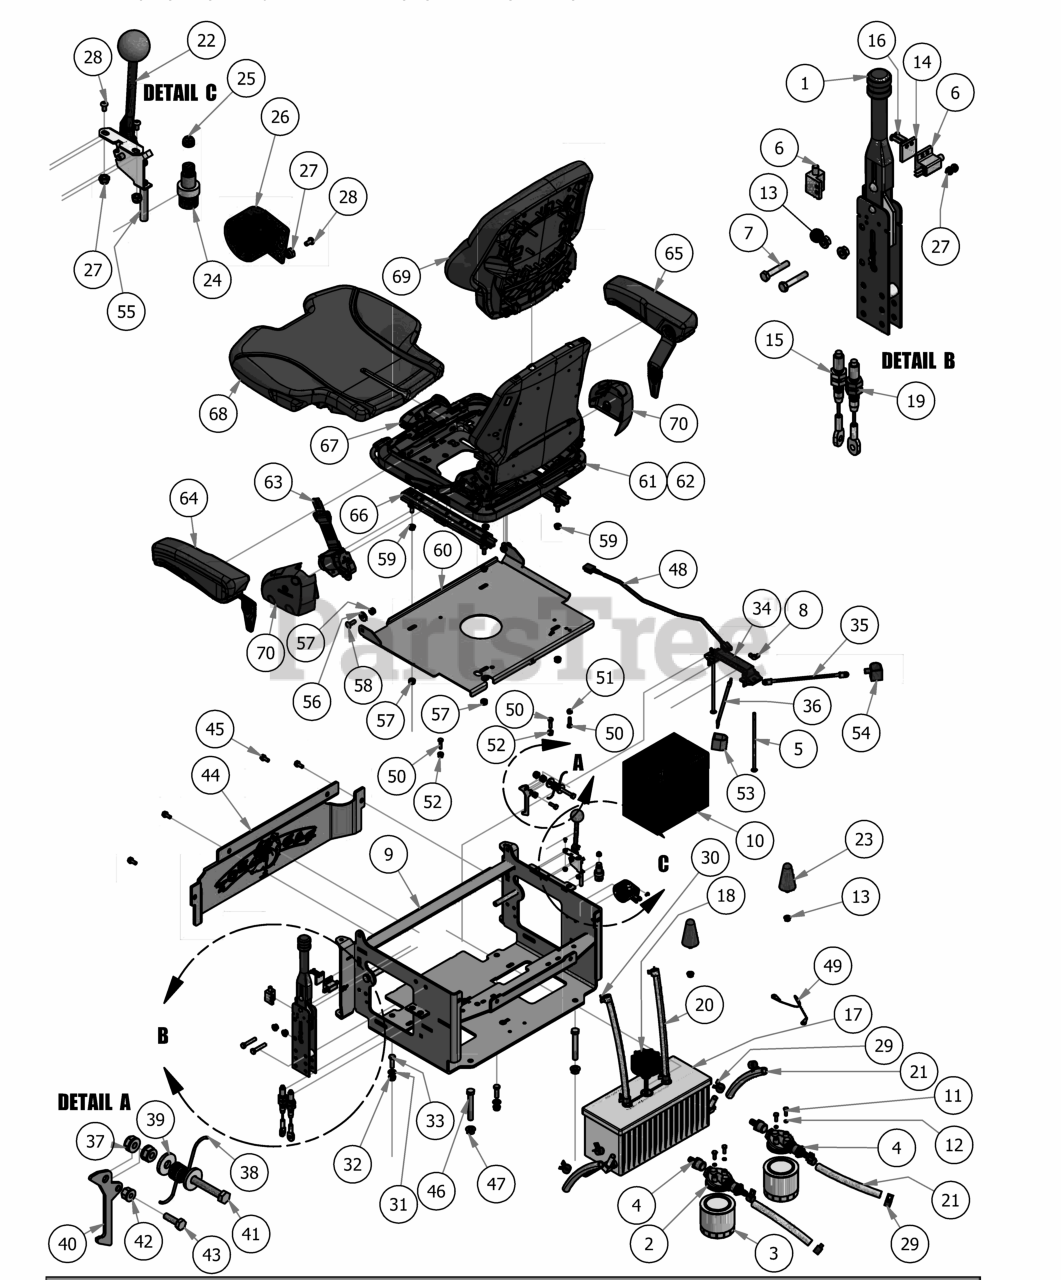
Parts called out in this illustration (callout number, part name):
1	Hand Brake Assembly
2	Filter Head
3	Hydraulic filter
4	Filter Head Fitting
5	1/4-20 X 9 Carriage Bolt
7	5/16" x 1 3/4" Hex Bolt
8	1/4" Wing Nut
9	2007 Diesel Seat Frame
10	Battery - Diesel Models - I51
11	1/4" x 3/4" Hex Bolt
12	1/4" Lock Washer
13	5/16" Flange Nut w/Serrations
14	Switch Block Plastic
15	Short Brake Cable
16	1024 x 1" Allenhead Bolt
17	Aluminum Hydraulic Tank
18	Hydraulic Tank Cap
19	Long Brake Cable
20	3/8" x 32" Clear Hose
21	1/2" x 9 1/4" Braided Hose
22	Universal Throttle Head
23	Spring Cushion
24	Momentary Start Switch
25	Start Switch Boot - Diesel
26	Heat Warning Piezo Buzzer
27	#10 Nylock Nut
28	1024 X 5/8" Buttonhead Bolt
29	1/2 Hose Clamp
30	3/8 hose clamp
31	3/8" Flat Washer
32	3/8" Flange Nut
33	3/8" x 1 1/4" Hex Bolt
34	Battery Hold Down
35	Black Battery Cable - Diesel
36	Red Battery Cable - Diesel
37	5/16-18 Nylon Flange Nut
38	Torsion Spring for Seat latch
39	.360 ID Plastic Washer
40	Seat Latch Lever
41	5/16-18 X 2 Hex C/S (GR.5) ZC
42	1/4-20 Nylon Insert flange Nut
43	1/4-20 x 1-1/4 GR 5 Hex Bolt
44	Cooler Cover
45	5/16 x 3/4 washer head type F screw
46	1/2 x 3 1/2 Flange Bolt Grade 8
47	1/2" Flange Nut
48	Seat Switch Adapter
49	Seat Cable
50	1/4-20 x 1 GR 5 hex bolt zinc
51	1/4 Nylock Nut
52	1/4-20 Nylon Insert flange Nut
54	Black Boot For Ground Cable
55	Diesel Throttle Cable Only
56	.360 ID Plastic Washer
57	5/16-18 Nylon Flange Nut
58	5/16" x 1" Carriage Bolt
59	5/16" Flange Nut
60	Seat Plate
61	Grammer Seat With Seatbelt
62	Grammer Seat Black and Orange
63	Grammer Seat Belt Kit
64	Left Armrest Kit for Grammer Seat
65	Right Armrest Kit for Grammer Seat
66	Rails for Grammer Seat (Pair)
67	Grey Handle Assembly for Grammer Seat
68	Black Seat Cushion for Grammer Seat
69	Black Back Cushion for Grammer Seat
70	Black Plastic Side Covers for Grammer Seat
